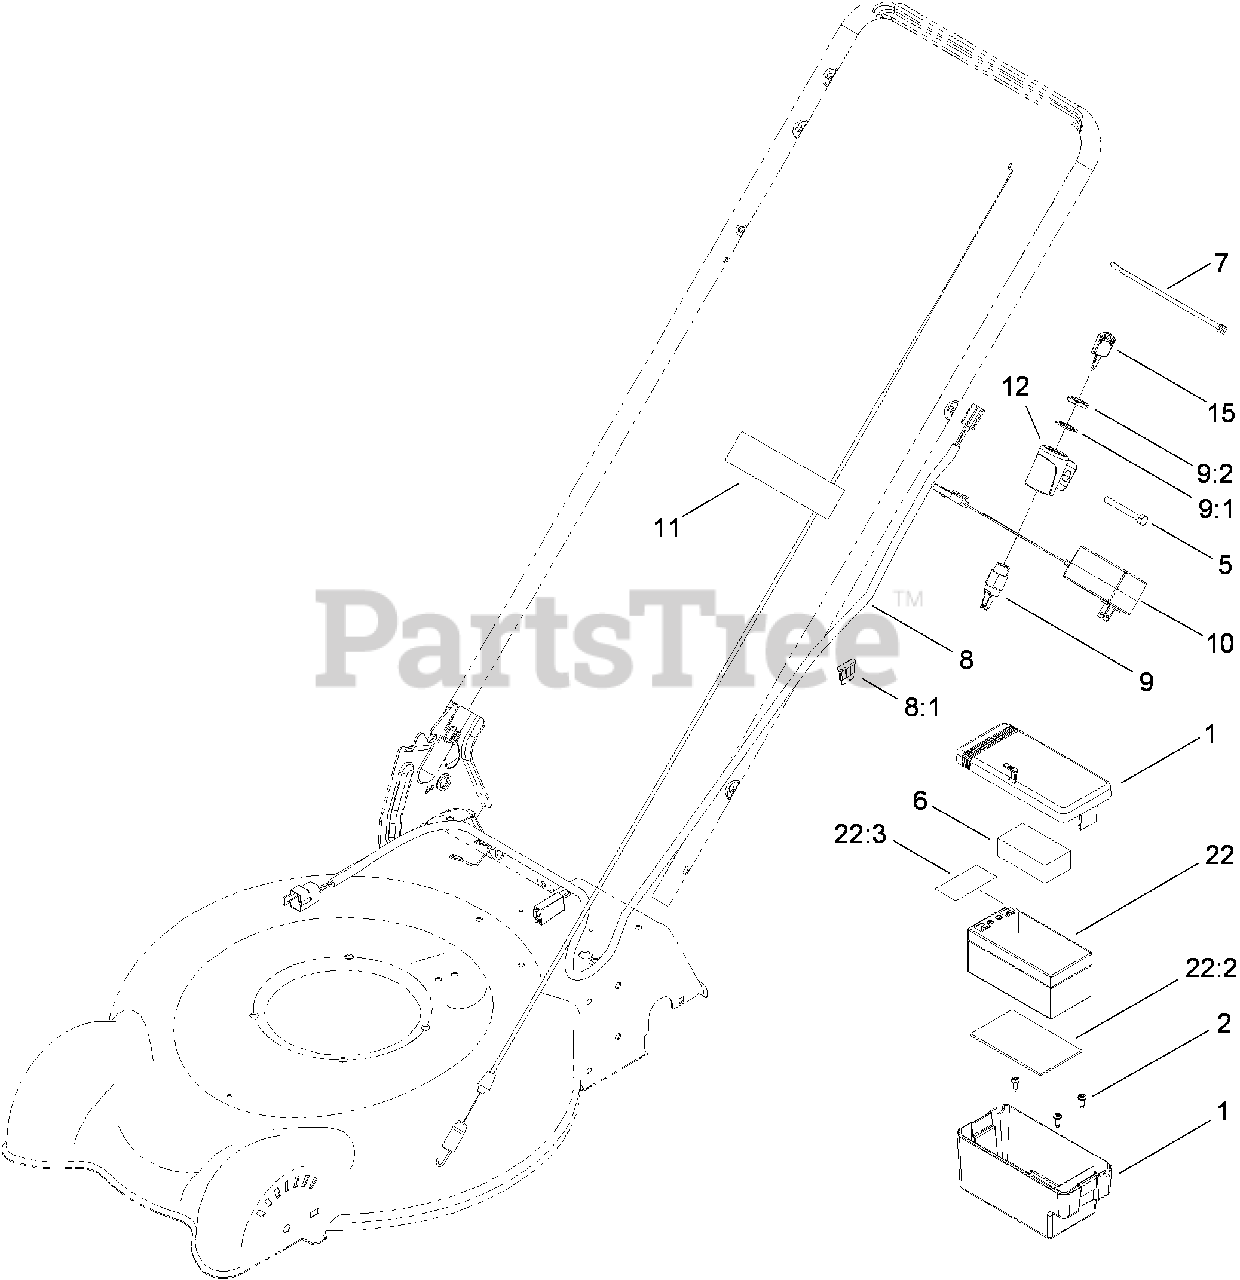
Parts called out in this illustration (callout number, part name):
1	BATTERY BOX ASM
2	SCREW-THREAD FORMING
5	SCREW-HH
6	FOAM-BATTERY, TOP
7	STRAP-TIE
8	HARNESS-WIRE
8:1	FUSE-40 AMP
9	STARTER SWITCH ASM
9:1	WASHER-TOOTH, INTERNAL
10	CHARGER-BATTERY
11	DECAL-HARNESS
12	MOUNT-SWITCH
22:2	FOAM-BATTERY
22:3	DECAL-TERMINAL, BATTERY
